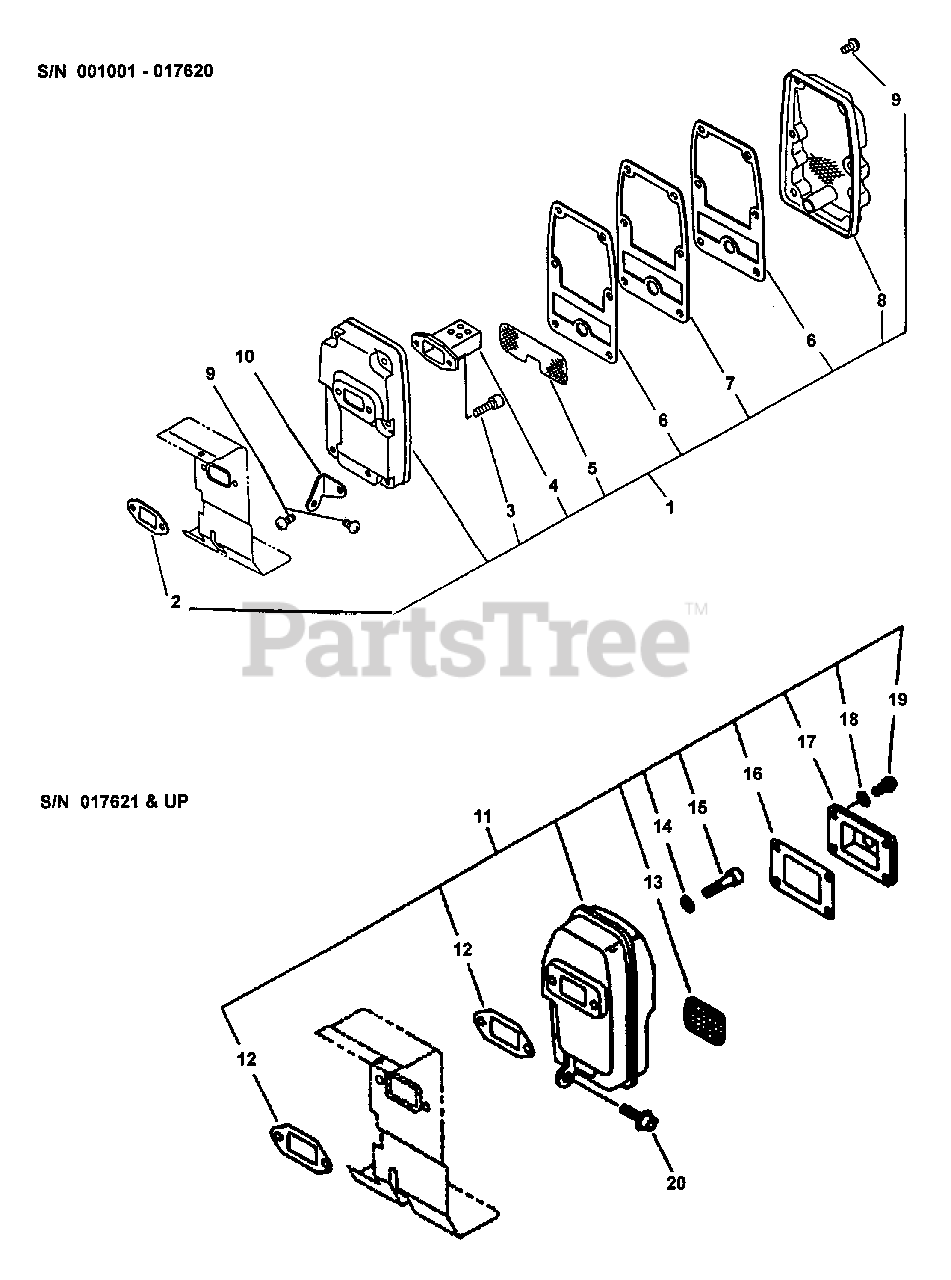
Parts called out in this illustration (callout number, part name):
1	MUFFLER ASSY
2	GASKET, EXHAUST
3	BOLT M5×18
4	BAFFLE, MUFFLER
5	SCREEN, SPARK ARRESTER
6	GASKET
7	SILENCER
8	COVER, MUFFLER
9	SCREW 5×16
10	STAY, MUFFLER
11	MUFFLER ASSY
12	GASKET, EXHAUST
13	SCREEN, SPARK ARRESTER
14	WASHER, FLAT 5.5×10×0.8
15	BOLT 5×60
16	GASKET, EXHAUST
17	GUIDE, EXHAUST
18	WASHER, SPRING 4 MM
19	SCREW - 4×12
20	BOLT 5×16
